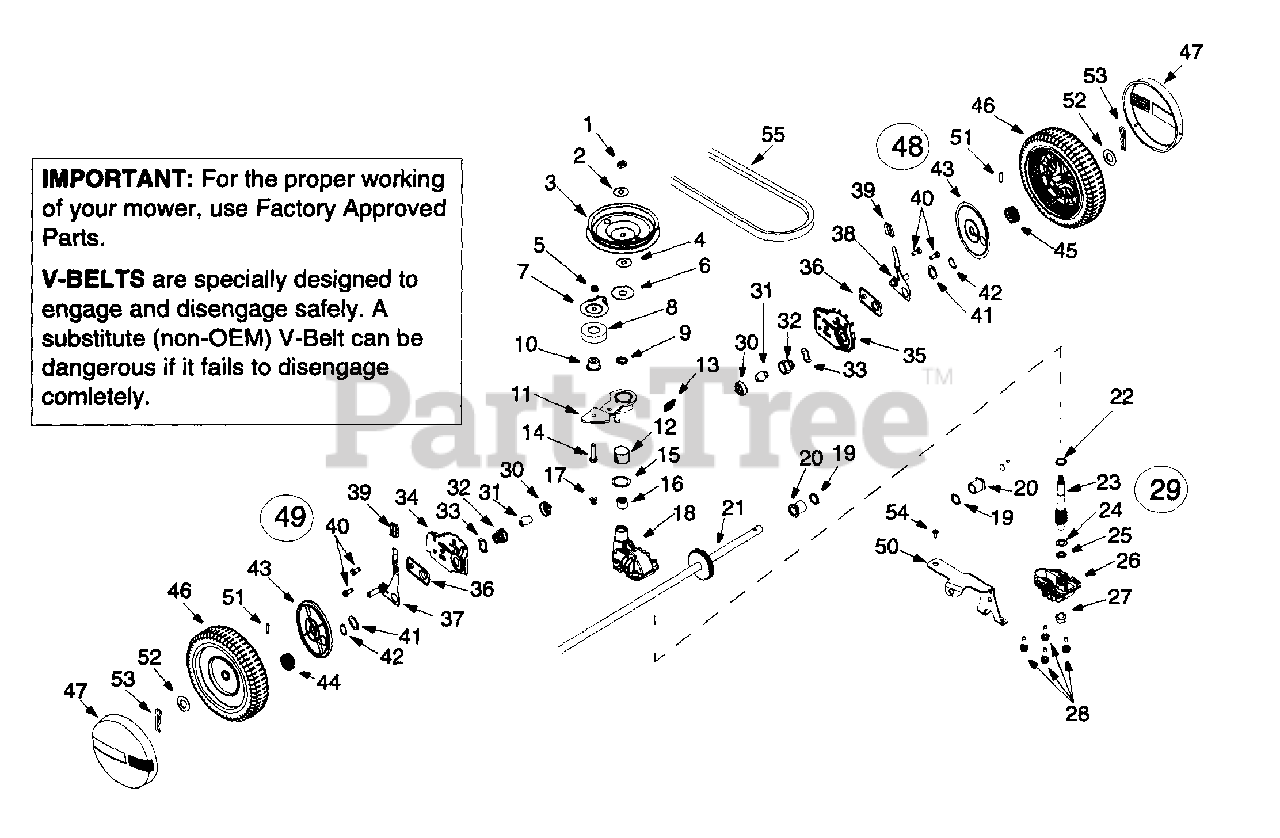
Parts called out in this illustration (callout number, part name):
1	Hex Jam Nut 5/16-24
2	Bell Wash .325 x .930 x .045
3	Pulley
4	Bell Wash .325 x .930 x .045
5	Hex Nut 1/4 - 28 Lock
6	Flat Wash .442 x 1.38 x .060
7	Belt Keeper
8	Ball Bearing
9	Oil Seal
10	Flange Spacer
11	Idler Bracket Assembly
12	Bearing Sleeve
13	Wash: Flat:.504 x .700 x .030
14	Hex Cap Screw 1/4-28 x 1.00 Gr. 5
15	Flat Washer .865 x 1.145 x .030
16	Needle Bearing .438 x .625 x .500
17	Plug 1/4 x .437
18	Housing Asm:Upper:
19	Seal:Oil: .500 x .687 x .094
20	Flange Bearing .503 x .689 x .792
21	Output Shaft
22	Flat Washer .504 x .700 x .030
23	Pinion Shaft 10T.
24	Thrust Washer .375 x .70 x .030
25	Thrust Washer .388 x .625 x .062
26	Housing:Lwr:
27	Flange Bearing .378 x .531 x .370
28	Hex Screw w/Wash 1/4-20 x .750
29	Transmission-Complete
30	Bearing Retainer
31	Bearing Sleeve .50 I.D.
32	Bearing Support
33	Wave Washer 1.5 x 1.0 x .029
37	Front Lever R.H
38	Front Lever L.H.
39	Knob
40	Hex Cap Screw 3/8-16 x .75
41	Washer DD 1.5" O.D.
42	Snap Ring 1.0 Dia
43	Wheel Dust Cap
44	Gear 14T RH Fwd
45	Gear 14T LH Fwd
46	Whl 8 x 1.75 Disk Bar Gray Sleeve S
47	Hubcap:Whl:Radial Spoke Grey
48	Height Adj. Complete RH
49	Height Adj. Complete LH
50	Cable Idler Bracket
51	Dowel Pin
52	Flat Washer 1/2 x 1.00 x .063
53	Cotter Pin .08 x 1.42
54	Screw, Shoulder .375 x .25AB: 1/4-20
55	"V"-Belt
